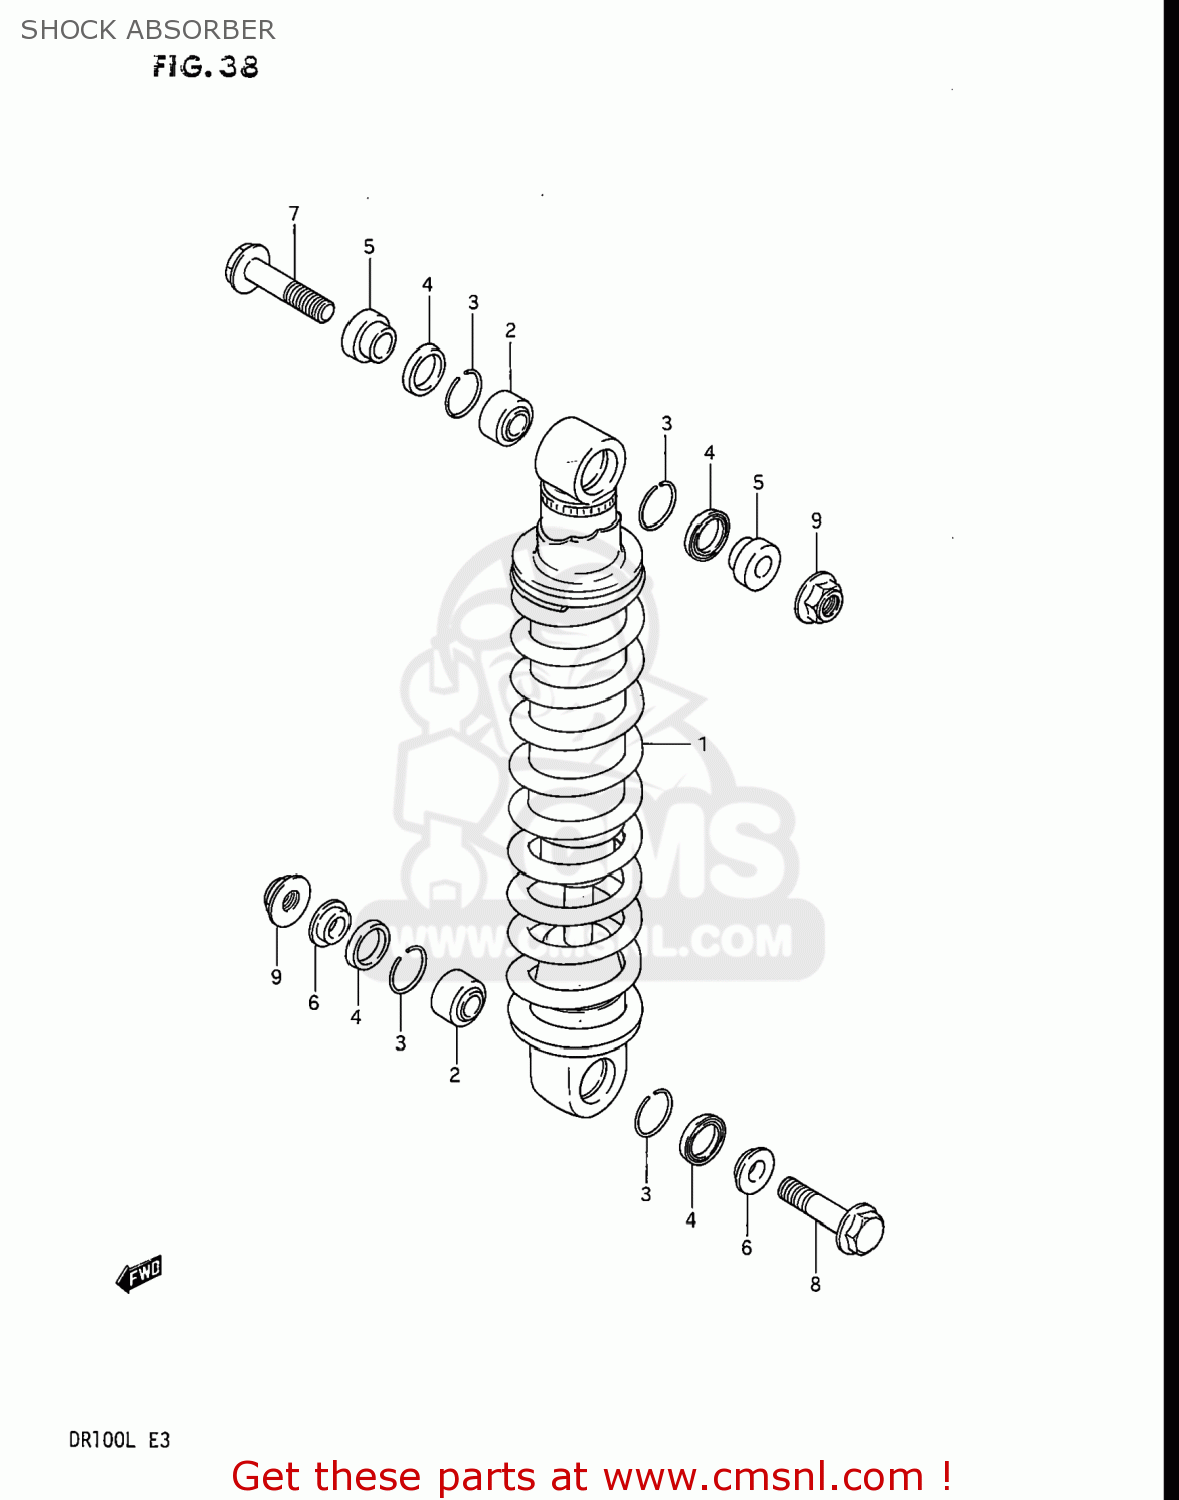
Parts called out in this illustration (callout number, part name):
1	ABSORBER ASSEMBLY,REAR SHOCK
2	BEARING,REAR SHOCK ABSORBER
3	RING
4	DUST SEAL
5	COLLAR
6	SPACER
7	BOLT(10X65)
8	BOLT(10X50)
9	NUT
